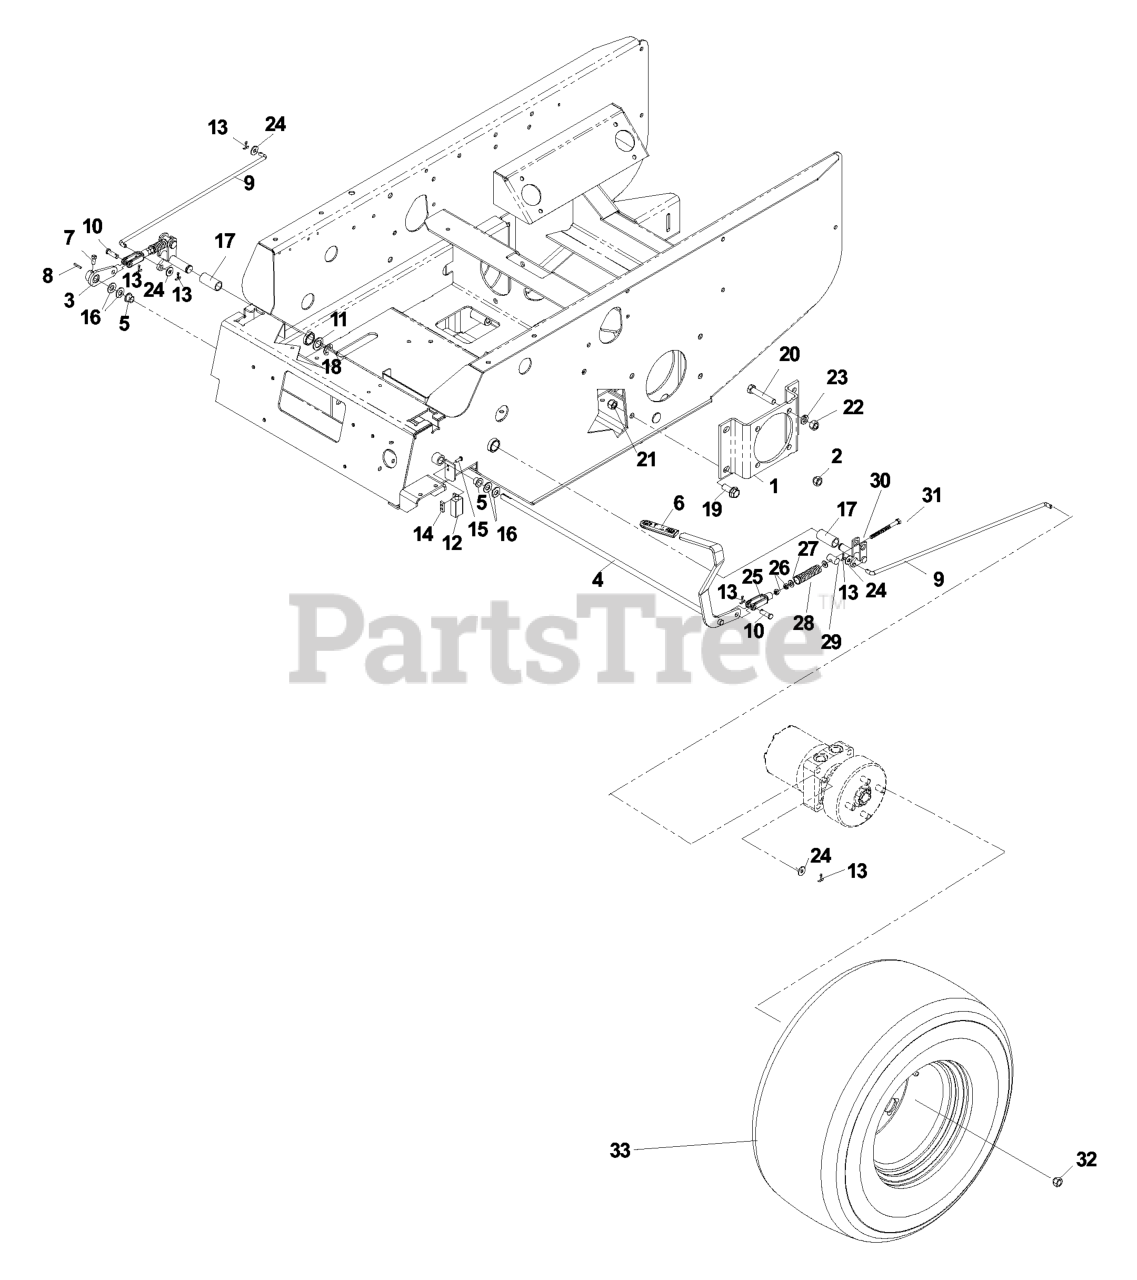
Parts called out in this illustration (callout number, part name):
1	MOTOR STANDOFF - PAINTED
2	LUG NUT 1/2F
3	BRAKE ARM WELDMENT
6	GRIP, PARK BRAKE
7	SCREW 5/16C X 5/8 SQ HEAD
9	BRAKE LINKAGE BAR
10	CLEVIS PIN 3/8 X 1 1/8
13	RP_COTTER PIN 1/8 X 3/4
14	TAPPED PLATE
15	SCREW #10-24 X 5/8
16	WASHER, 7/16 DISC SPRING
17	BRONZE BEARING
18	E RING 3/4
19	HCS 1/2C X 1 1/4 SERRATED HEAD
20	HCS 1/2C X 2 3/4
21	NUT 1/2-13 HEX NYLOC ZD
22	NUT HEX 1/2
23	WASHER 1/2" SPLIT LOCK
24	WASHER 5/16 FLAT
25	YOKE-3/8-24 PLTD
27	WASHER 3/8 SAE FLAT
29	TRUNION PIN
31	HCS 3/8F X SPECIAL
32	LUG NUT 1/2F
33	TIRE/WHEEL ASSY 26 X 12-12
